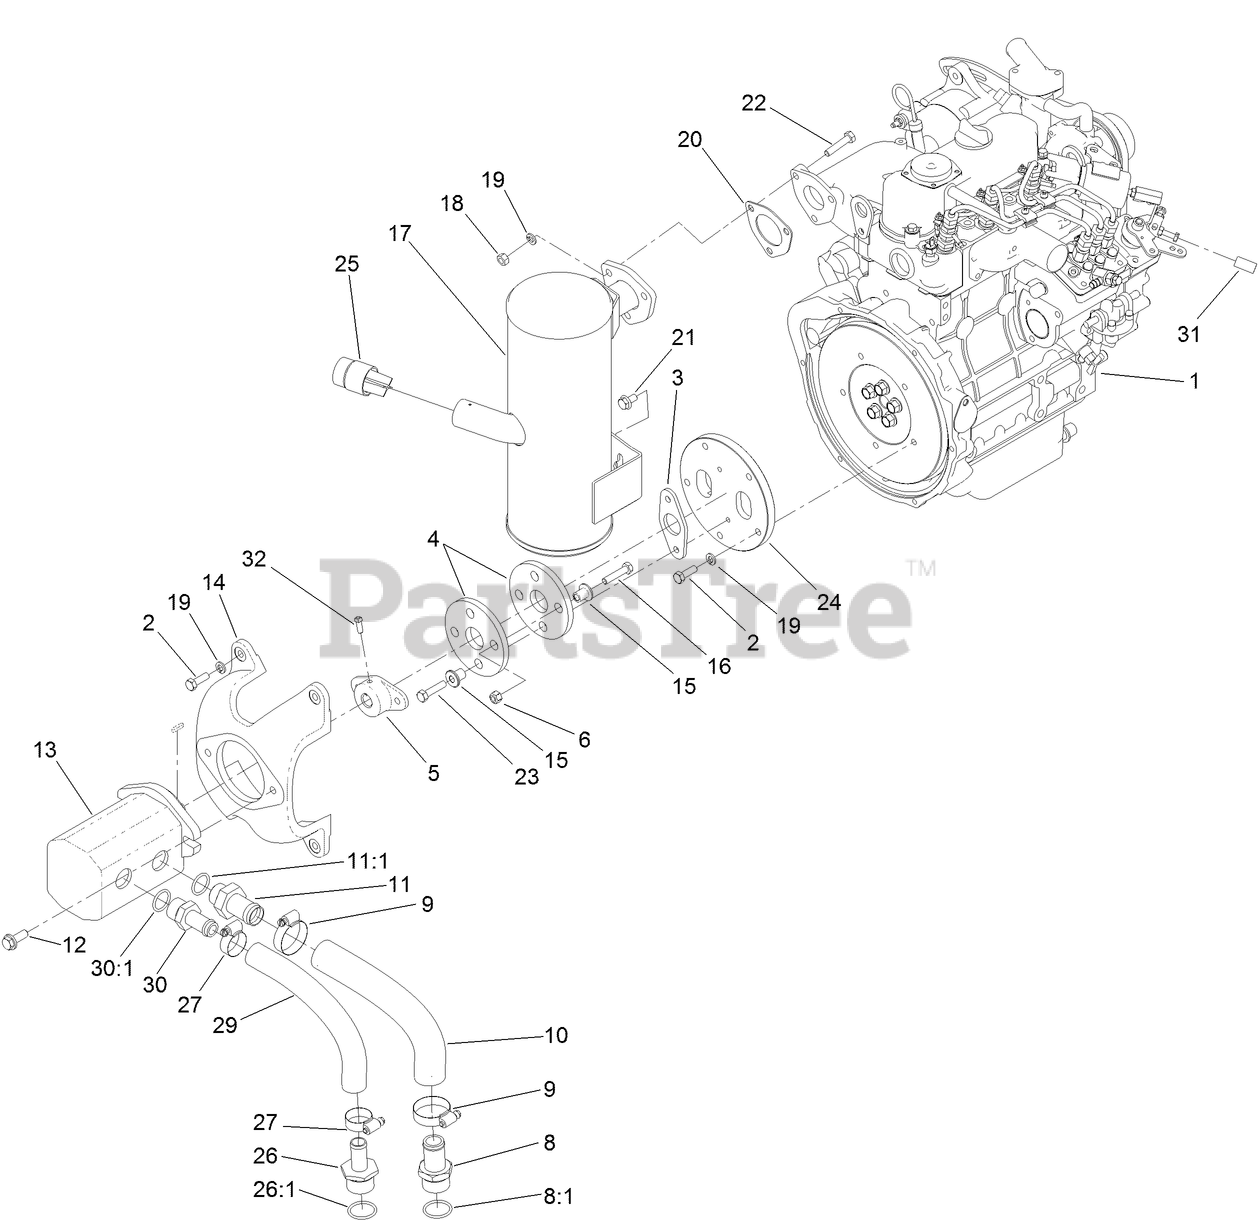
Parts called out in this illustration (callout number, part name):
1	ENGINE-KUBOTA, D722
3	SPACER-COUPLER
4	COUPLING-RUBBER
5	HUB-PUMP
6	NUT-LOCK
8	FITTING-STR
8:1	O-RING
10	HOSE-SUCTION
11	FITTING
11:1	O-RING
12	SCREW-HHF
13	PUMP-GEAR, TANDEM
14	MOUNT-PUMP
15	SPACER
16	SCREW-HH
17	MUFFLER
18	NUT-HEX
19	WASHER-LOCK
20	GASKET-MUFFLER
21	SCREW-HHF, LOCK
22	SCREW-HH
24	ADAPTER-FLYWHEEL
25	SCREEN-ARRESTER, SPARK
26	FITTING-STR
26:1	O-RING
27	CLAMP-HOSE
29	HOSE SUCTION
30	FITTING
30:1	O-RING
31	TUBE-ALUMINUM
32	SCREW-SET
